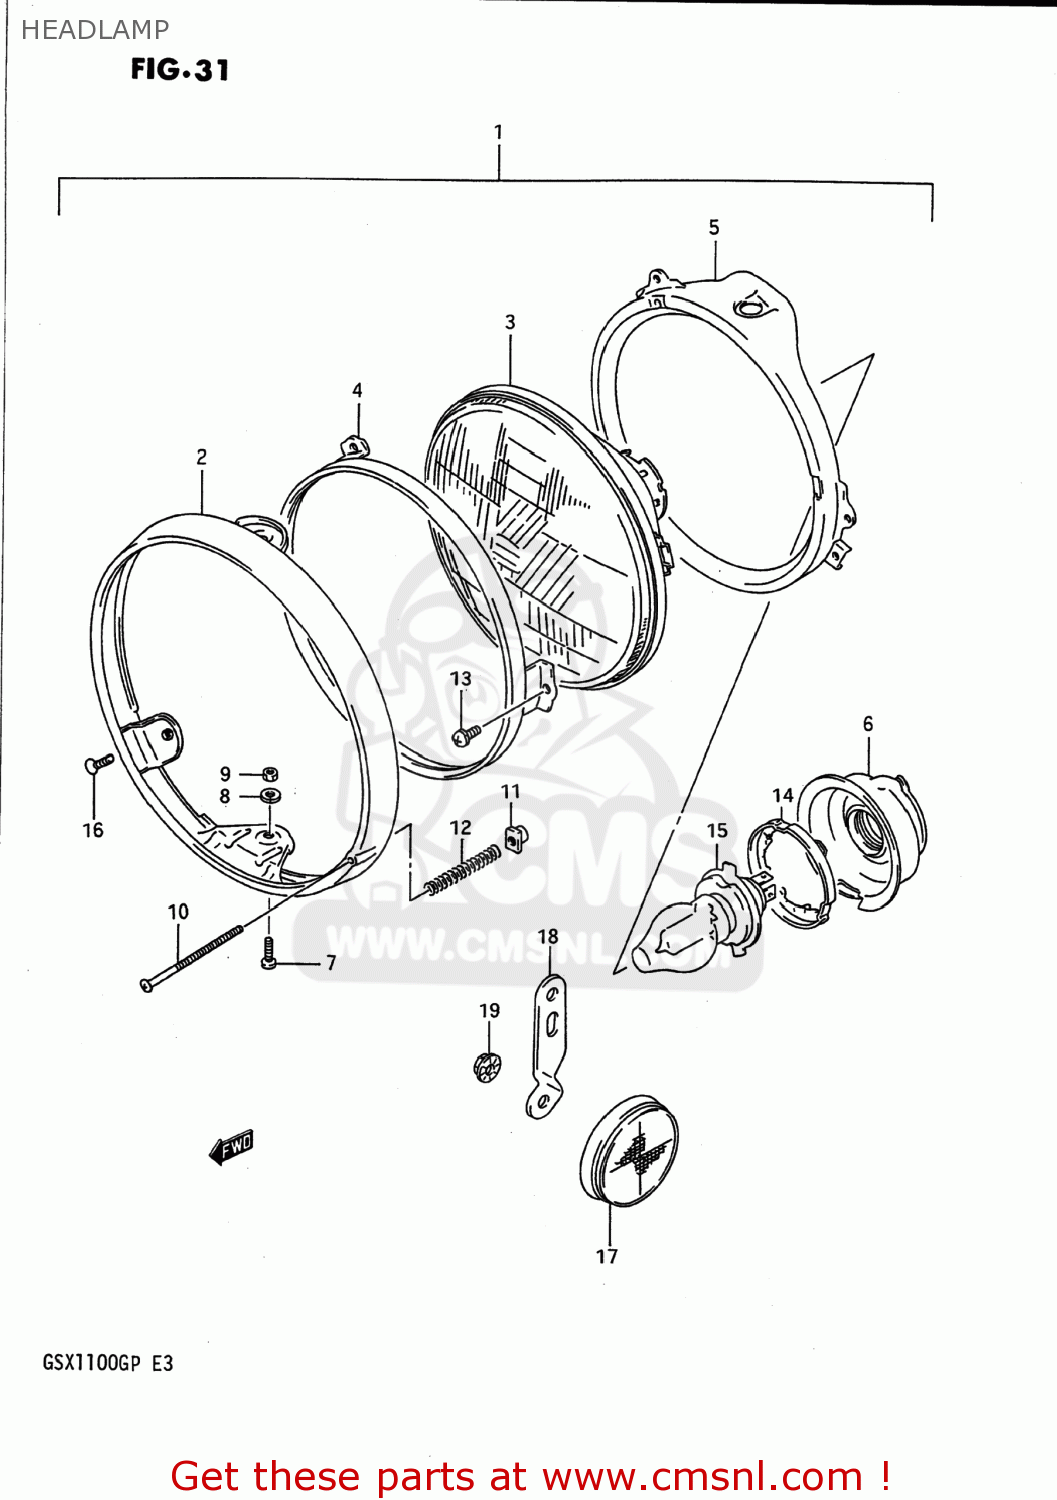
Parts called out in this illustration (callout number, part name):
1	HEADLAMP ASSY
2	RIM,HEADLAMP
3	LAMP UNIT
4	RETAINING RING
5	RING
6	COVER,HEADLAMP SOCKET
7	H/LAMP LENS UNIT FITING SCRE
8	LOCK WASHER
9	NUT
10	SCREW,HEADLAMP ADJUST
11	NUT
12	SPRING,ADJUSTING
13	SCREWM4X0.7X10
14	SETTING,BULB
15	BULB(12V60/55W,H4)
16	SCREW 5X12
17	REFLECTOR,REFLEX FR
18	BRACKET,FRONT SIDE REFLECTOR
19	NUT
